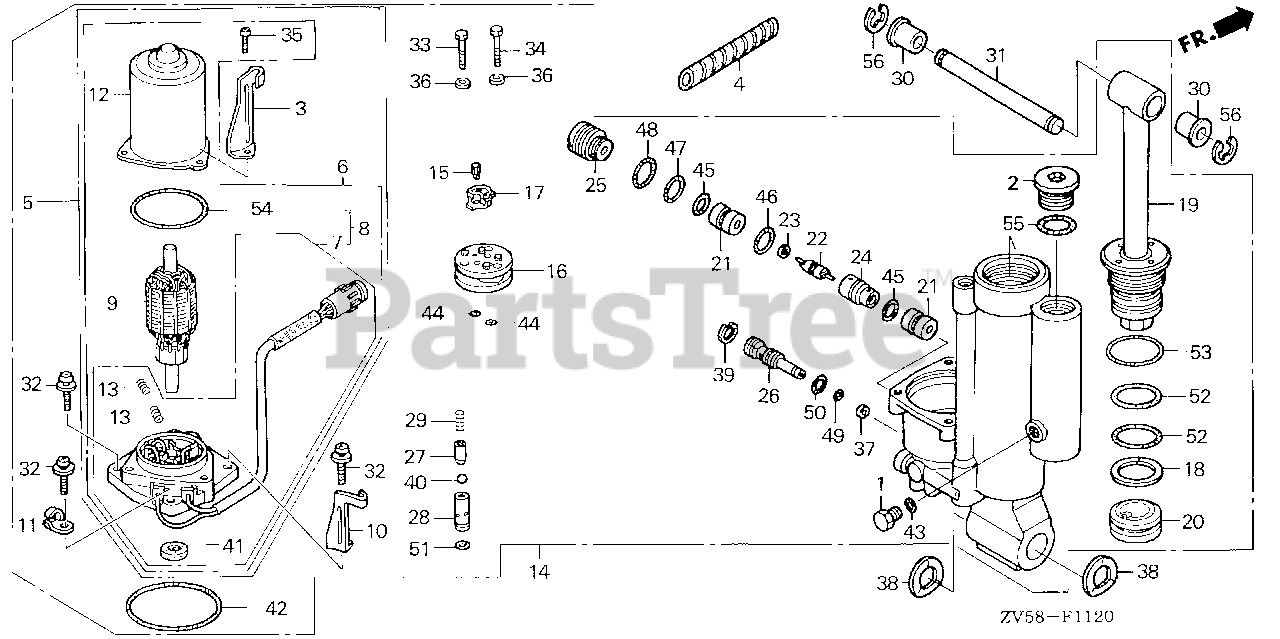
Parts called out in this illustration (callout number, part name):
1	CAP, OIL HOLE
2	CAP, OIL HOLE
3	CLAMP, WIRE
4	TUBE, SPIRAL
5	MOTOR ASSY., POWER TILT
6	MOTOR ASSY., POWER TILT
7	BRACKET ASSY.
8	BRACKET ASSY.
9	ARMATURE
10	HOLDER, HARNESS
11	CLAMP, WIRE
12	YOKE
13	SPRING, MOTOR
14	TRIM-TILT ASSY., POWER *NH283* (STIN GRAY)
15	JOINT, DRIVE (NOT AVAILABLE)
15	JOINT, DRIVE
18	RING, BACK-UP
19	ROD, PISTON
19	ROD, PISTON (NOT AVAILABLE)
20	PISTON, FREE (NOT AVAILABLE)
20	PISTON, FREE
22	SPOOL, VALVE
23	RING, BACK-UP
25	PLUG C
26	VALVE, MANUAL
26	VALVE, MANUAL (NOT AVAILABLE)
27	GUIDE, SPRING
28	SEAT B, VALVE
29	SPRING B, VALVE
30	BUSH, CYLINDER (UPPER)
31	PIN, CYLINDER (UPPER)
32	SCREW-WASHER
33	BOLT A, SOCKET
34	BOLT B, SOCKET
35	SCREW, PAN (5X16)
35	SCREW, PAN (5X20)
36	WASHER, PLAIN
37	WASHER, SEAL
38	WASHER, WAVE (26MM)
39	CIRCLIP (INNER)
40	BALL, STEEL
42	O-RING (1.8X69.6)
43	O-RING (1.9X8.8)
44	O-RING (1.5X6.5)
46	O-RING (1.5X13.5)
47	O-RING (1.5X15.5)
48	O-RING (1.5X19.5)
49	O-RING (1.5X5.5)
50	O-RING (2.4X9.8)
51	O-RING (1.5X3.5)
52	O-RING (3.5X38.7)
53	O-RING (2.0X44.5)
54	O-RING
55	O-RING (1.9X27.7)
56	E-RING (10MM)
